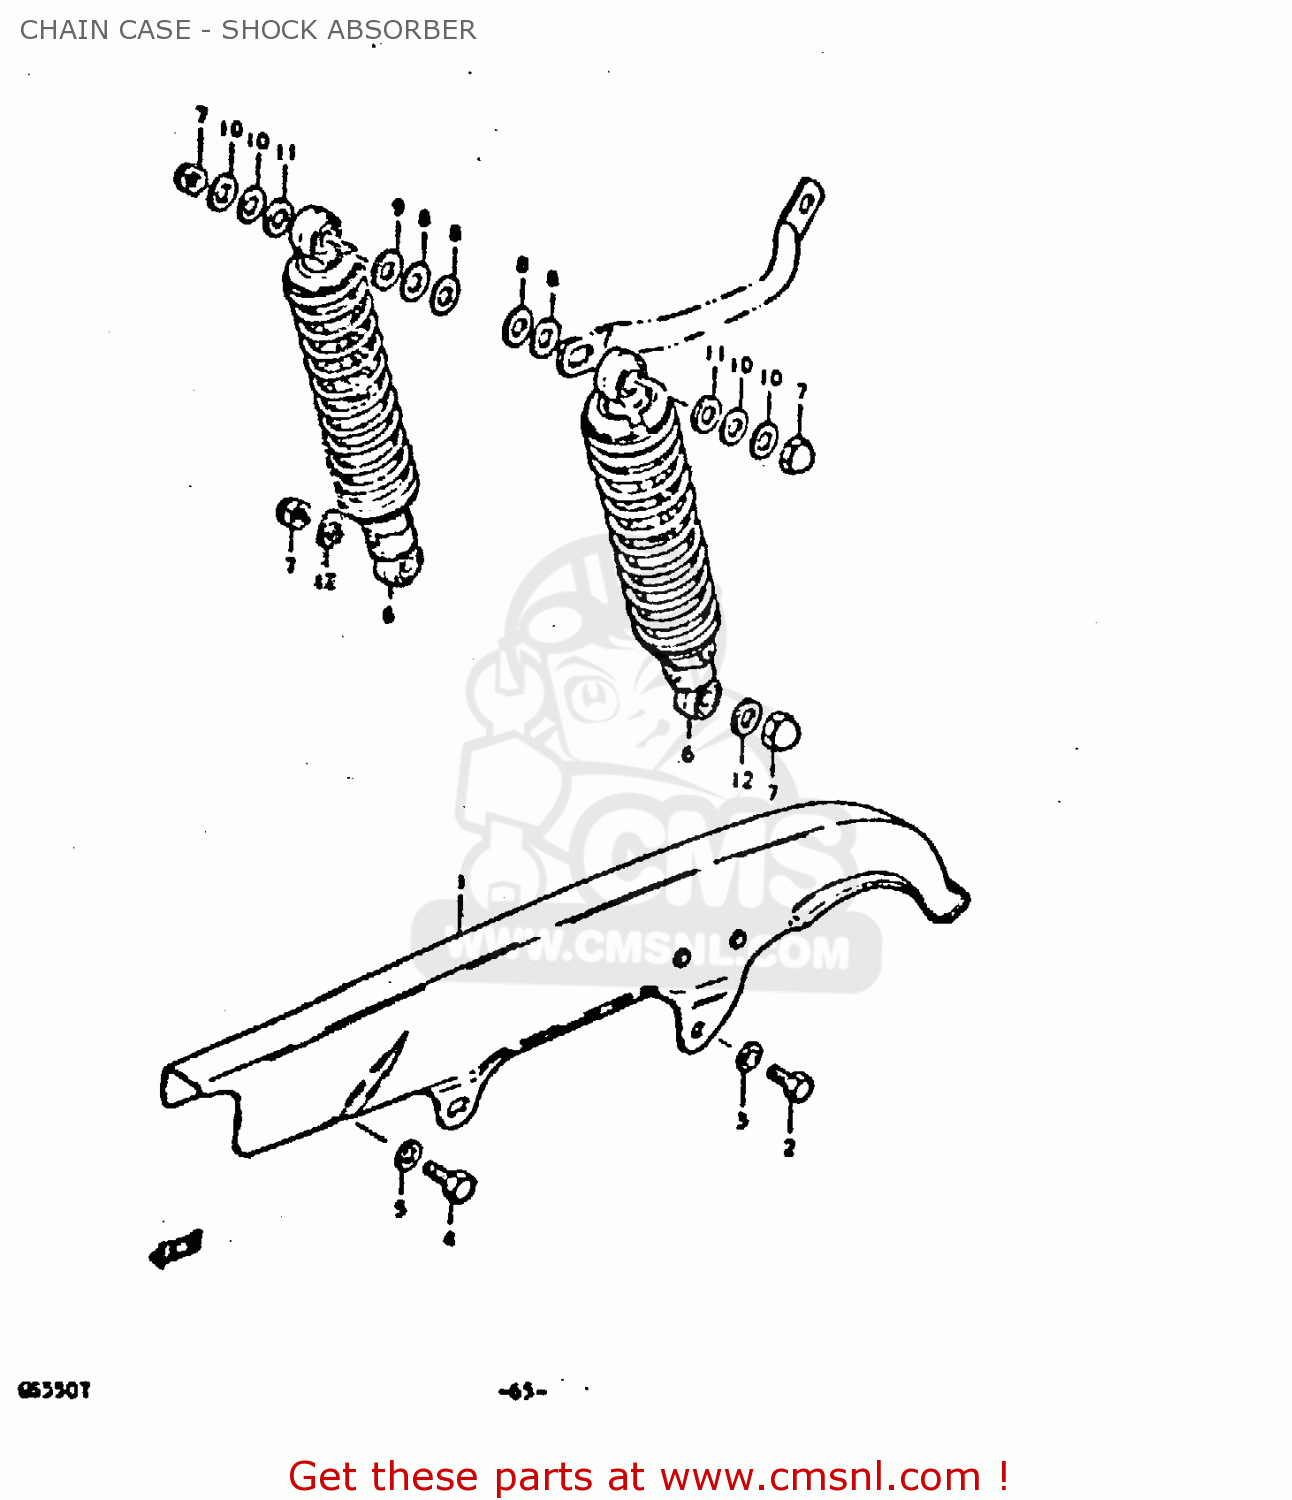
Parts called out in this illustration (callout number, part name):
1	CASE,CHAIN
2	BOLT(6X8)
3	WASHER
4	BOLT
5	WASHER(6.5X18X1)
6	ABSORBER ASSEMBLY,REAR SHOCK
7	NUT, LOWER LH
8	WASHER
9	WASHER (12.5X24X3.2)
10	WASHER
11	WASHER(10.5X24X3.2)
12	WASHER
